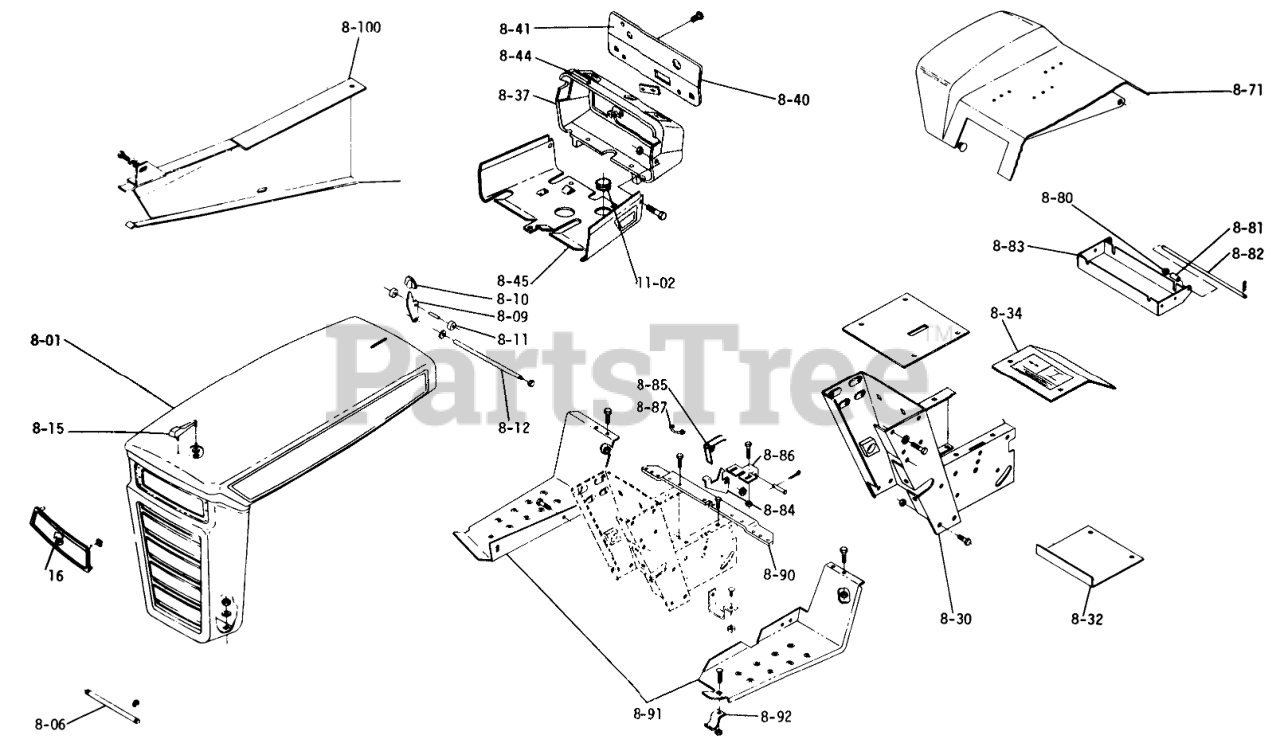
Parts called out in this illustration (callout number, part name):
8-01	Bracket-Grille Support
8-01	Bolt Hex 5/16-18
8-01	Nut-Nylok
8-06	GRILL PIVOT ROD
8-06	Lock Rod
8-09	LEVER HOOD LATCH
8-09	SPIROL PIN
8-10	KNOB
8-12	Plate-Cover
8-12	Nut-Hi Crown
8-12	Cotter Pin
8-12	ROD-HOOD STOP
8-15	Hood Ornament
8-16	ESCUTCHEON PLATE
8-16	SPEED NUT
8-30	Bolt 3/8-16 x 1
8-30	Washer
8-30	Plate Cover Hoodstand
8-30	Bolt, 1/4-20 Whizlock
8-32	Cover-Dust
8-32	Bolt 5/16-18 x
8-32	Nut-Nylok
8-34	Plate-Shift
8-34	Bolt, 1/4-20 Whizlock
8-37	Screw 5/16-18 x 3/4 S.T.
8-37	Bolt 1/4-20 x 5/8 Whizlock
8-37	Nut-Nylok
8-71	Fender
8-72	Bolt Hex 5/16-18 x 3/4
8-72	Nut-Nylok
8-72	GROMMET
8-81	Spacer
8-82	Rod-Sat Pivot
8-82	Hairpin
8-83	Tool Box
8-83	Bolt Hex 5/16-18 x 3/4
8-83	Nut-Nylok
8-83	Bolt 3/8-16 x 1
8-85	Spring
8-85	NYLINER BUSHING
8-85	Hairpin
8-86	Bolt-1/4-20 x 5/8
8-86	Nut-Nylok
8-90	Bolt 5/16-18 x 1
8-90	Bolt, 5/16-18 X 7/8
8-90	Nut-Nylok
8-91	Bolt 5/16-18 x
8-91	Nut 5/16-18
8-91	Bolt, 5/16-18 x 1/2
8-91	Pad-R.H. Footrest
8-92	BRACKET
8-92	Bolt-Carriage 5/16-18
8-92	Nut 5/16-18
8-100	Assy.-Belt Guard-85
8-100	Bolt, 5/16-18 x 1/2
8-100	Bolt 3/8-16 x 3/4
8-100	Lockwasher
8-100	Washer
